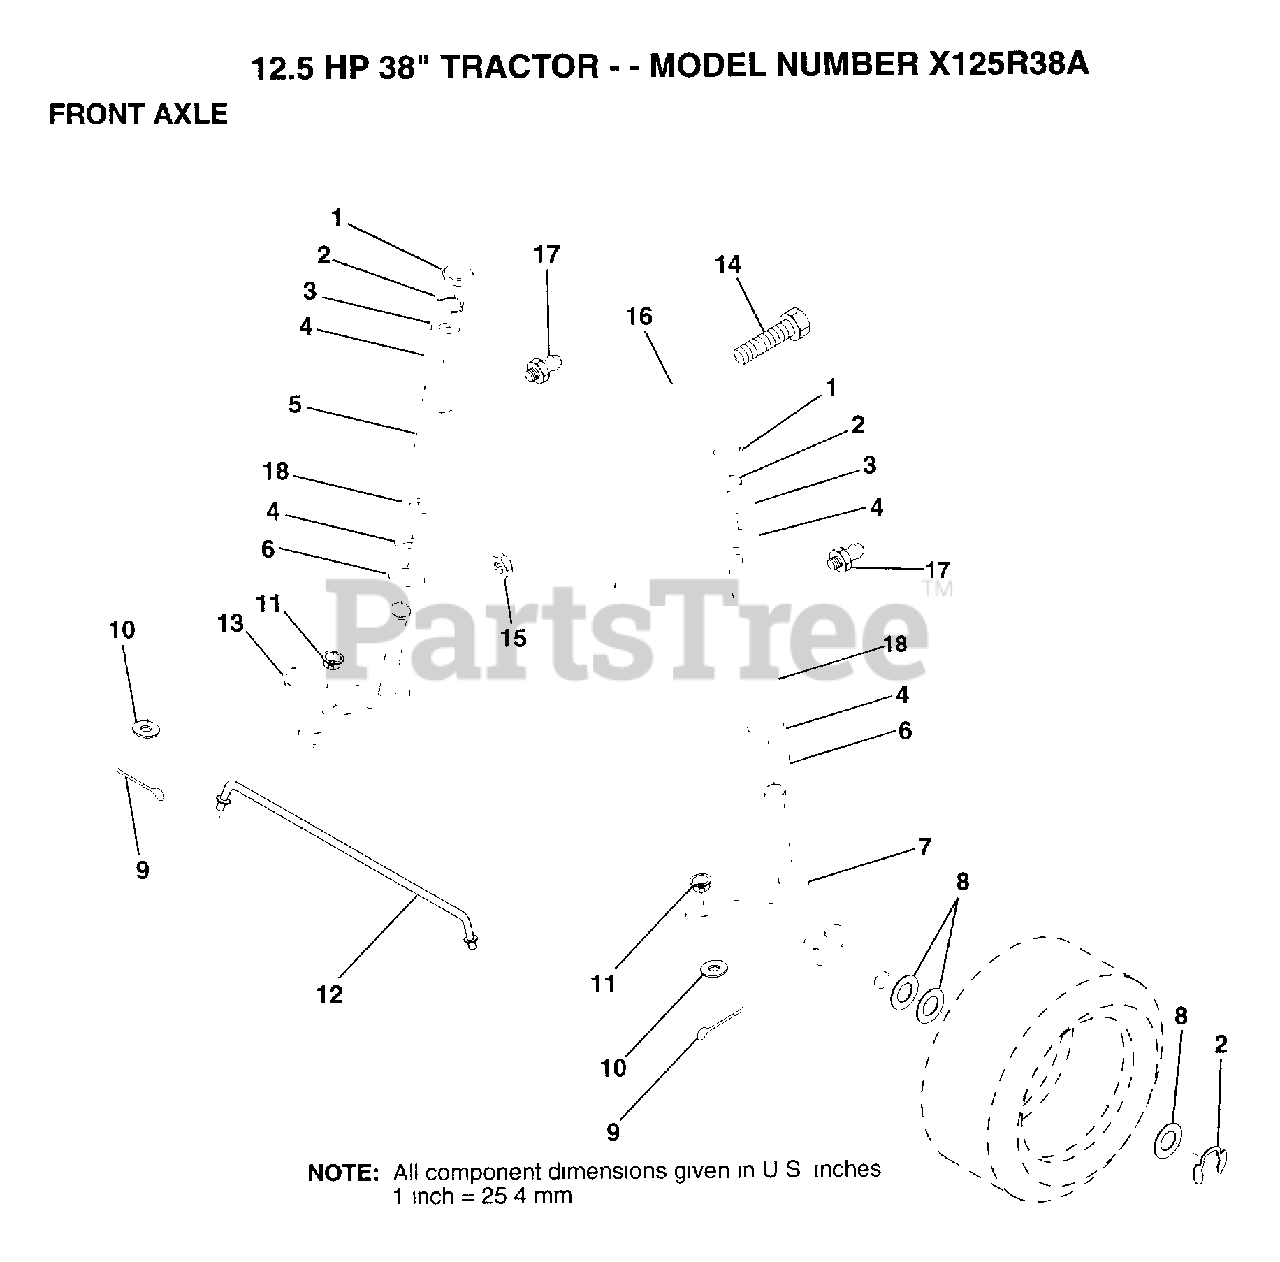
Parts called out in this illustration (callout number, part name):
1	CAP
2	RING
3	WASHER
4	COL. SRTG. BEAR.
6	WASHER .T
7	SPINDLE ASM RH
8	WASHER
9	COTTER PIN
10	WASHER
11	BUSHING.DRAGLINK
12	TIE ROD
13	SPINDLE ASM LH
14	BOLT HEX 5/8-11
15	"NUT-LOC,FLANGE LT"
16	BEARING
17	ZERK M
18	WASHER
